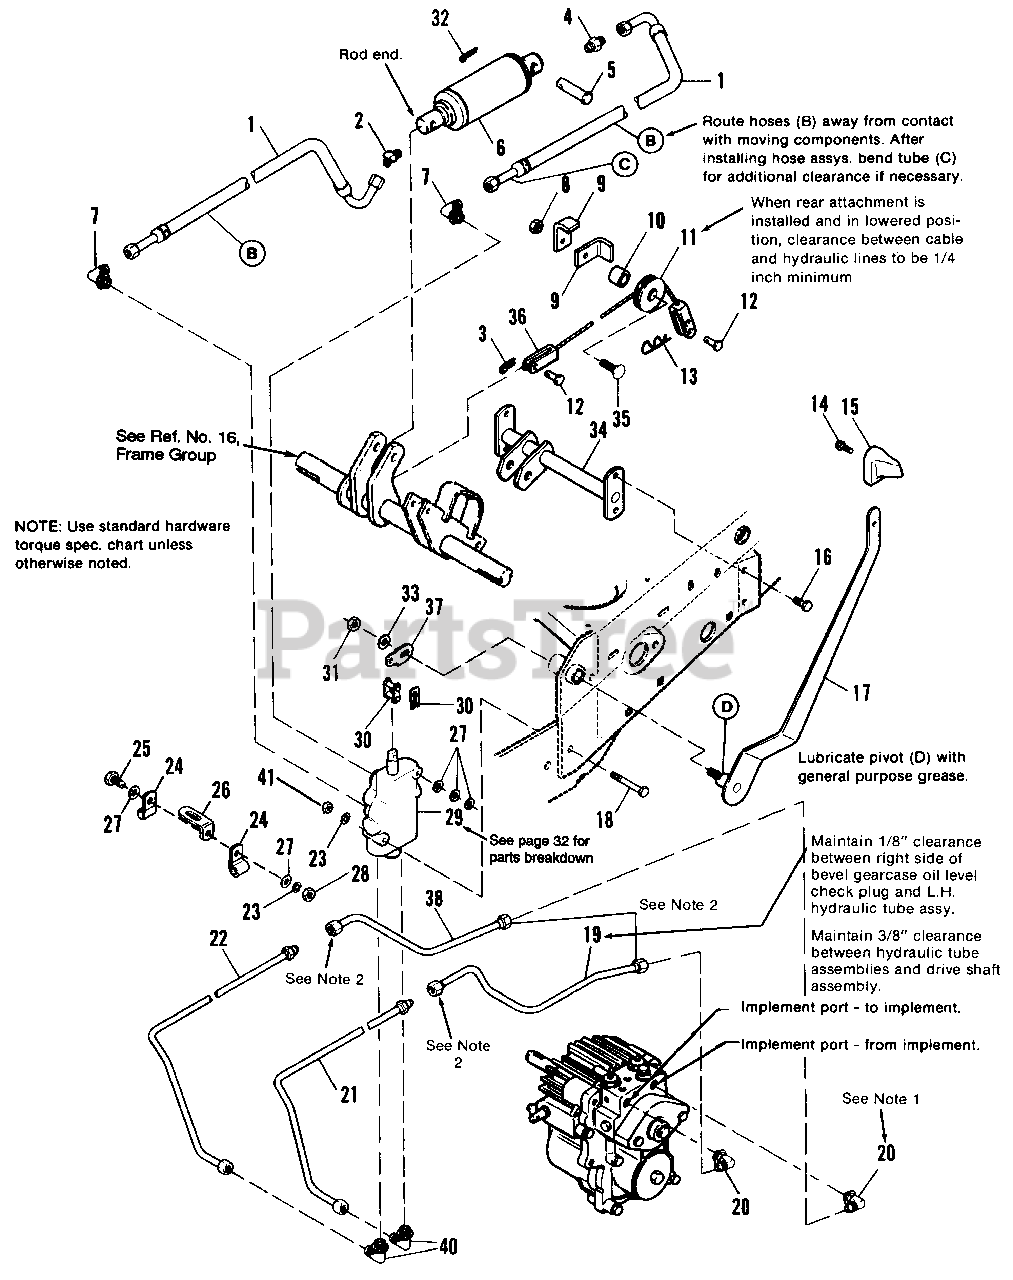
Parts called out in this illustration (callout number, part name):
1	HOSE, Hydraulic
2	ELBOW, 45ø Male
3	PIN, Cotter, 3/32 x 3/4
4	CONNECTOR, 37ø Male
6	CYLINDER, Hydraulic (Incl. Ref. No. 2)
7	ELBOW, Adjustable, 37ø
8	LOCKNUT, Hex, Jam, 3/8-16
9	GUARD, Cable
13	CLIP, Spring
14	SCREW, Hex, Washer Hd., Plastite, 1/4-20 x 1
15	KNOB, Soft (All except Mfg. Nos. 1692143 & 1692144)
15	KNOB, (Mfg. Nos. 1692143 & 1692144)
16	SCREW, Hex, Washer Hd., Taptite, 3/8-16 x 3/4
17	LEVER ASSY.
18	CAPSCREW, Hex Hd., 1/4-20 x 2
20	FITTING, Hydraulic
23	LOCKWASHER, 1/4
25	CAPSCREW, Hex Hd., 1/4-20 x 1-1/4
27	WASHER, Plain, 1/4
28	NUT, Hex, Full, 1/4-20
29	CONTROL VALVE ASSY. (See following 2 pages)
30	LINK, Connecting
31	NUT, Hex, Lock, 3/8-16
33	WASHER, Plain, 3/8
34	SUPPORT ASSY.
36	CABLE ASSY.
39	CLIP, Hairpin
40	FITTING, Hydraulic
41	NUT, Hex, Flange, Whizlock, 1/4-20
